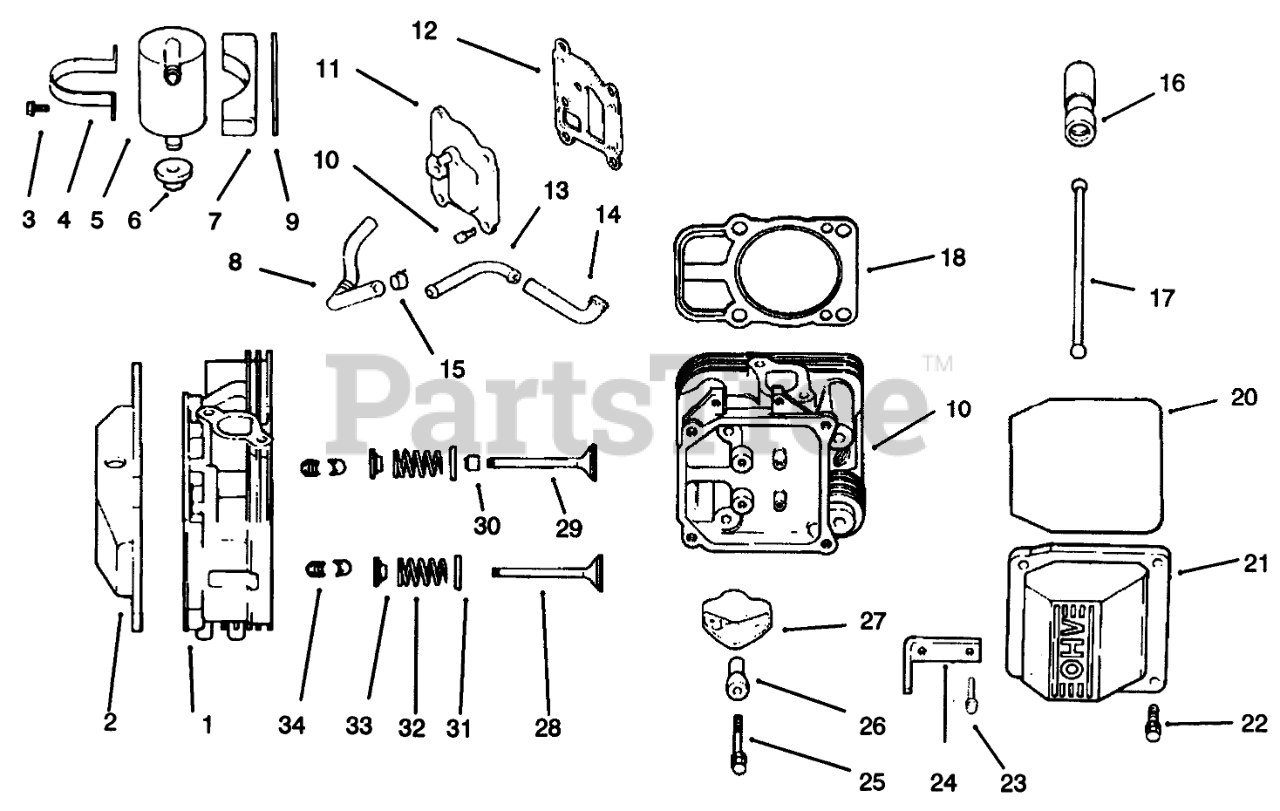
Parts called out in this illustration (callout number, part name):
1	Head ASM-#1 Cylinder
2	Kit-Valve Incl 6 20-22
3	Screw-HF
4	Strap-Breather
5	Kit-Breather Incl 3-9
6	Grommet-Rubber
7	Bracket-Breather Sep
8	Hose-Breather
9	Spacer
10	Screw
11	Cover-Breather
12	Gasket-Breather
13	Fitting
14	Hose-Breather
15	Clamp-Hose
16	Lifter-Valve
17	Rod-Push
18	Gasket-Cylinder Head
19	Head ASM-#2 Cylinder
21	Kit Valve Incl 20-22
22	Screw-Shoulder
23	Screw
24	Strap-Lifting
26	Pivot-Rocker Arm
27	Arm-Rocker
28	Valve-Exhaust
28	Valve-Exhaust (.25)
29	Valve-Intake
29	Valve-Intake (.25)
30	Seal-Valve Stem
31	Retainer-Spring
32	Spring-Valve
33	Cap-Valve Spring
34	Kit-Retainer
